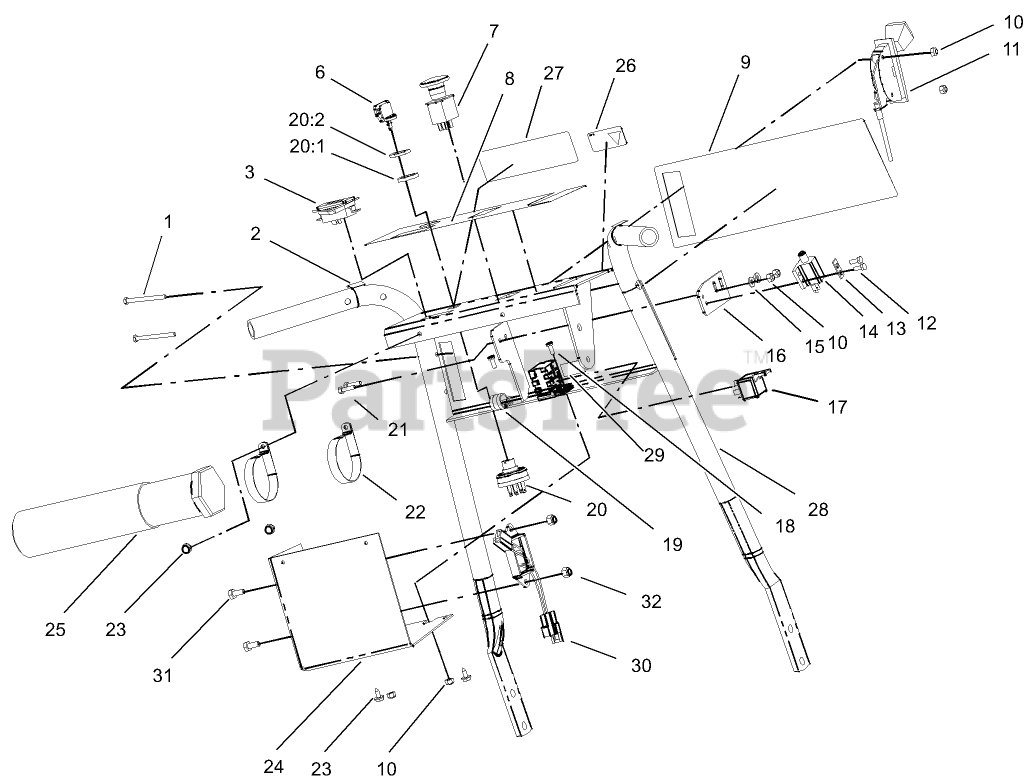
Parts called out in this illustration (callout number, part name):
1	SCREW-SHH
2	DECAL-LOCK, NEUTRAL
3	HOURMETER
6	KEY-IGNITION
7	SWITCH-PTO
8	Decal-Warning
9	DECAL-PROLINE
10	NUT-LOCK, NI
11	CONTROL-THROTTLE
12	SCREW-TAPTITE
13	PLATE-SWITCH
14	SWITCH-POLE, SINGLE
15	WASHER-FLAT
16	PLATE-MOUNTING, SWITCH
18	SCREW-HWH
19	CLAMP-R
20	SWITCH-ON / OFF
20:1	NUT-HH
20:2	WASHER-TOOTH, INTERNAL
21	SCREW-HWH
22	CLAMP-R
23	SCREW-HWHTF
24	BRACKET-COVER
25	TUBE-MANUAL
26	DECAL-PROTECTION, EAR
27	DECAL-WARNING
28	Handle ASM
29	DECAL-RELAY, 24 VOLT
30	Module-Filter
31	SCREW-HH
32	NUT-LOCK, NI
